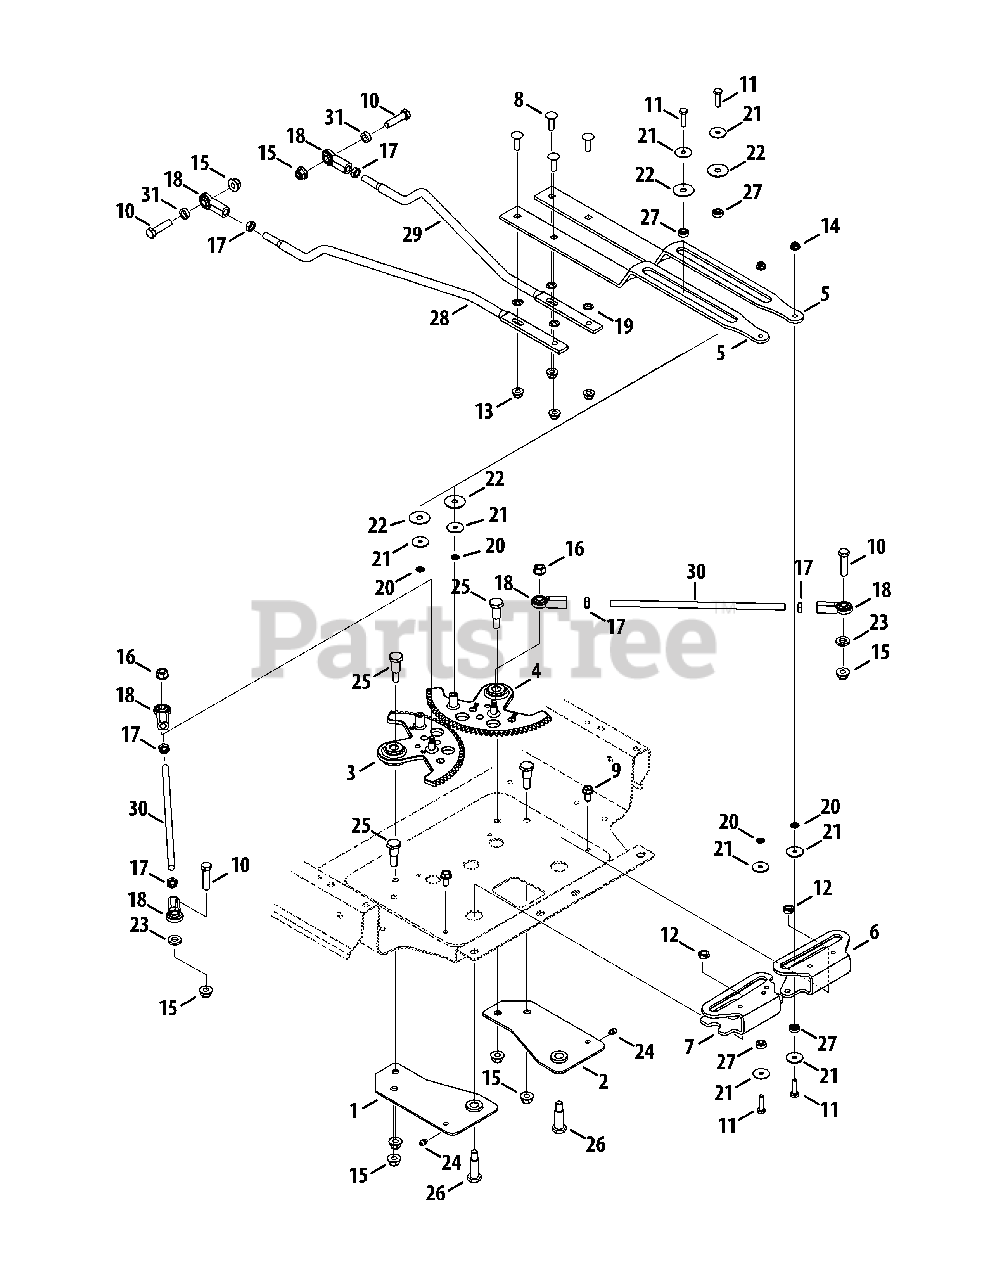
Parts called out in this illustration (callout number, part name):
1	Steering Plate Assembly, RH
2	Steering Plate Assembly, LH
3	Steering Gear Assembly, RH
4	Steering Gear Assembly, LH
5	Control Link
6	Speed Cam Plate, LH
7	Speed Cam Plate, RH
8	Carriage Screw, 5/16-18 x 1.00
9	Hex Washer Screw, 5/16-18 x .750
10	Hex Screw, 3/8-16 x 1.50
11	Hex Screw, 1/4-20 x 1.00
12	Nut, Jamlock, 3/8-16
13	Flange Lock Nut, 5/16-18
14	Flange Lock Nut, 1/4-20
15	Flange Lock Nut, 3/8-16
16	Nut, 5/16-18, Centerlock
17	Jam Nut, 3/8-24
18	Female Ball-Joint
19	Speed Nut, .3125 ID
20	Push Nut, .25 ID x .50 OD
21	Flat Washer, .285 x 1.25 x .060
22	Washer, .355 x 1.25 x .048
23	Flat Washer, .407 x .812 x .135
24	Grease Fitting, 3/16
25	Shoulder Screw, 3/8-16 x .625 x .875
26	Shoulder Screw, .500 x 1.25 x 3/8-16
27	Ball Bearing, .25 x .625
28	Hydro Link, RH
29	Hydro Link, LH
30	Drag Link, .375 Dia.
31	Spacer, .380 ID x .625 OD x .21
